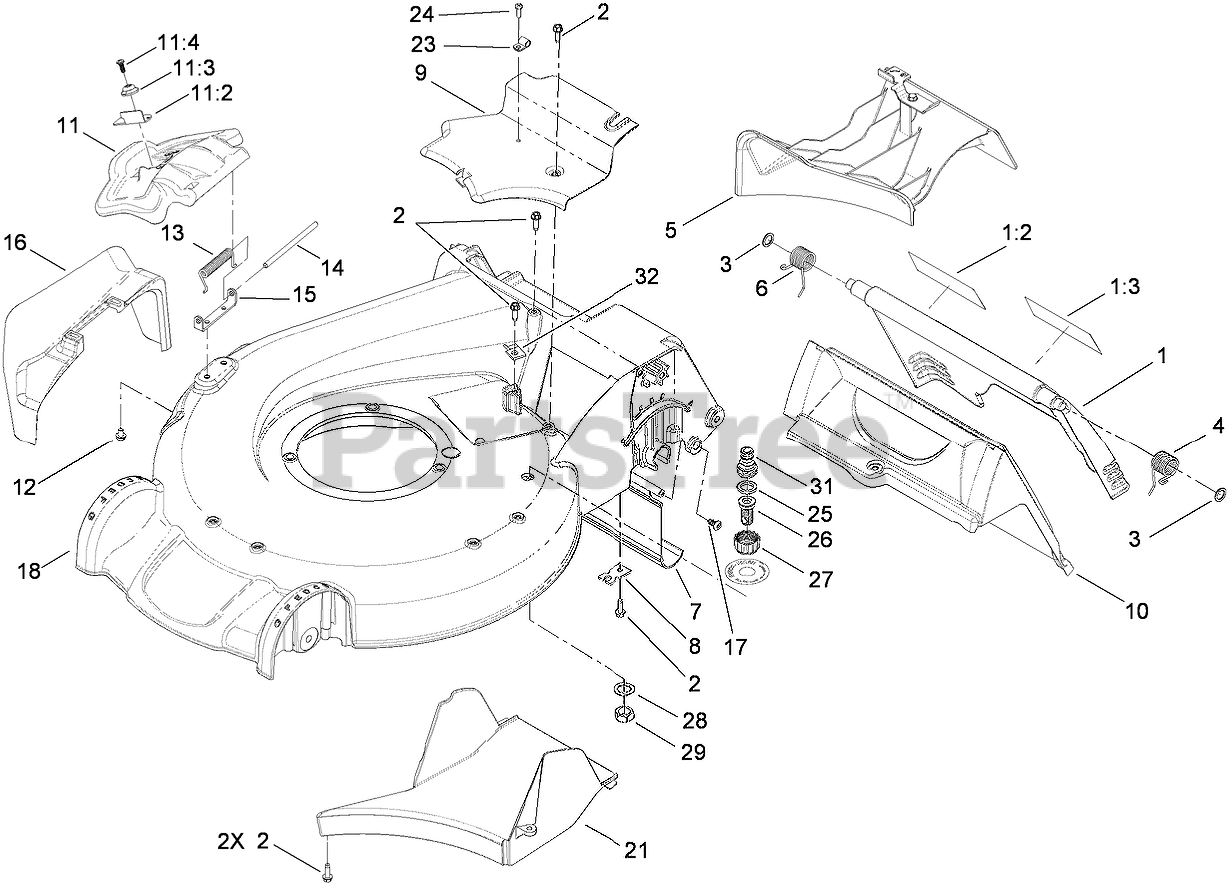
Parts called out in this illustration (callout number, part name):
1	REAR DOOR ASM
1:2	DECAL-WARNING
1:3	DECAL-WARNING
2	SCREW-HWHTF
3	WASHER-NYLON
4	SPRING-TORSION
5	MULCH PLUG ASM
6	SPRING-TORSION
7	SHIELD-TRAILING
8	BRACKET-CABLE, TRACTION
9	COVER-BELT
11	DISCHARGE DOOR ASM
11:2	LATCH-DOOR
11:3	CAP-DOOR
11:4	SCREW-PLASTITE
12	SCREW-HWH
13	SPRING-TORSION
14	ROD-COVER
15	BRACKET-COVER
16	CHUTE-DISCHARGE, SIDE
17	SCREW-PTH
18	HOUSING ASM
21	TUNNEL-DISCHARGE
23	CLAMP
25	WASHER-SEAL, WASHOUT PORT
26	PORT-WASHOUT
27	COUPLING-HOSE, WASHOUT PORT
28	WASHER-TOOTH, INTERNAL
29	NUT-JAM
31	ADAPTER-CONNECT, QUICK
32	CLAMP-CABLE
